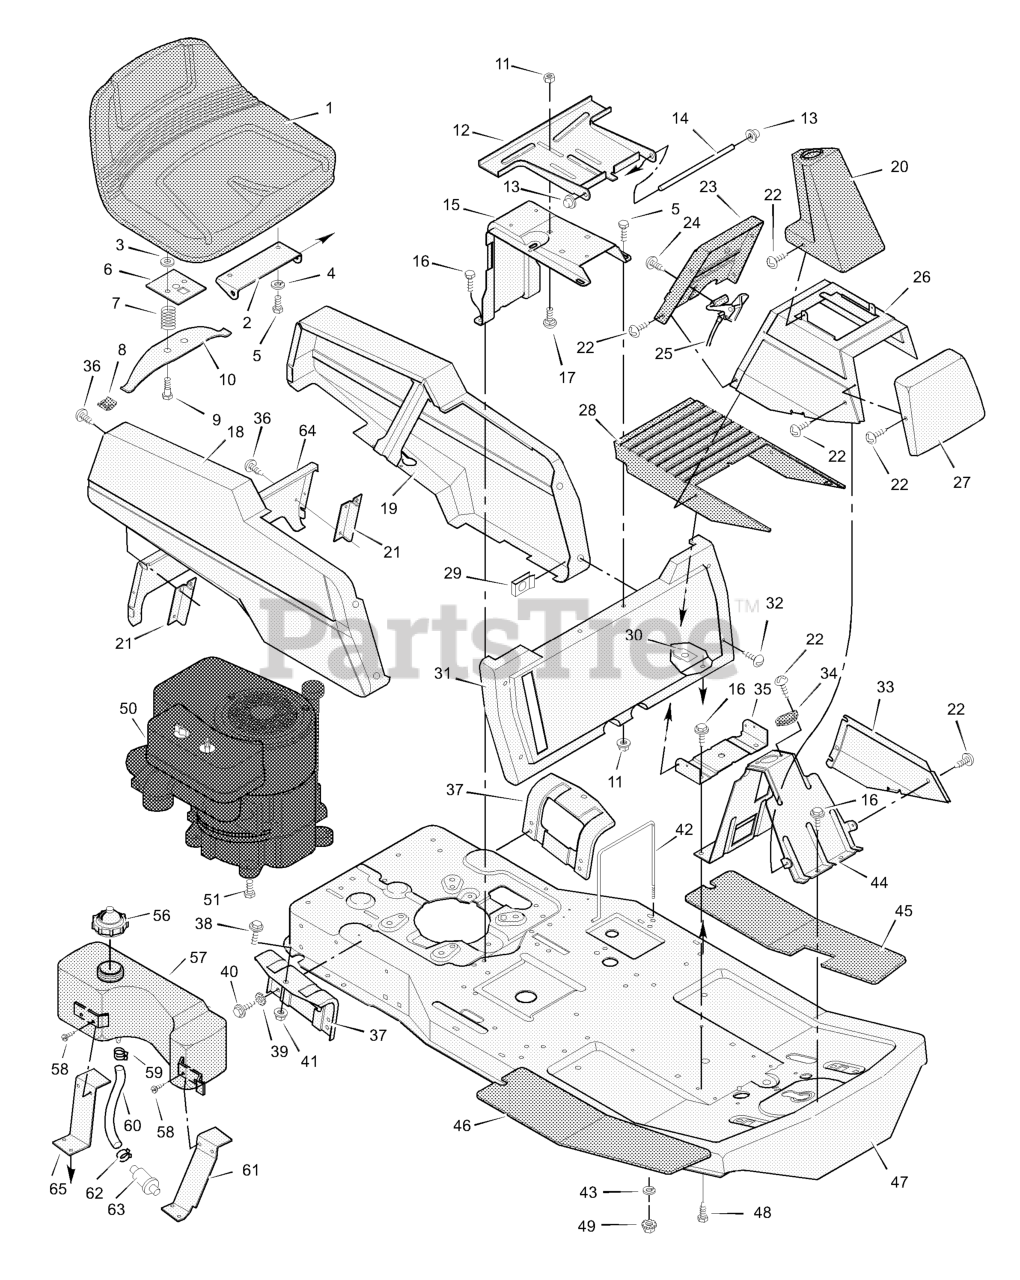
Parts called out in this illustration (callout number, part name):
2	Hinge, Seat
3	Retainer
4	LOCKWASHER
5	BOLT, Hex
6	Plate, Seat Switch
7	SPRING, Compression
8	Glide, Seat Spring
9	BOLT, Shoulder
10	SPRING, Seat
11	Locknut, Flange
12	BRACKET, Seat Pivot
13	Cap, Push On
14	ROD, Seat Hinge
15	SUPPORT, Seat
17	BOLT, Carriage
18	PANEL, Right Side
19	PANEL, Left Side
20	Cover, Steering Column
21	BRACKET, Panel
22	SCREW, Tapping
23	PANEL, Control
25	Throttle Control
27	Cap, Front Console
28	Cover, Lower Console
29	Retainer
31	PANEL, Front
32	SCREW, Southco
33	PANEL, Left Access
34	BEARING, Steering Post
35	BRACKET, Cover Mounting
37	SUPPORT, Body
38	BOLT, Shoulder
39	LOCKWASHER
41	Locknut, Flange
42	Clamp Assembly, Battery
44	SUPPORT, Steering Column
45	Mat, Left
46	Mat, Right
49	Locknut
50	Engine
51	BOLT, Engine Mount
56	Cap, Fuel
57	Tank, Fuel
58	SCREW, Hex
59	Clamp, Hose
60	LINE, Fuel
61	BRACKET, Remote Tank (Front)
62	CLAMP, Gas Line
63	Filter, Fuel
64	PANEL, Rear
65	BRACKET, Remote Tank (Rear)
